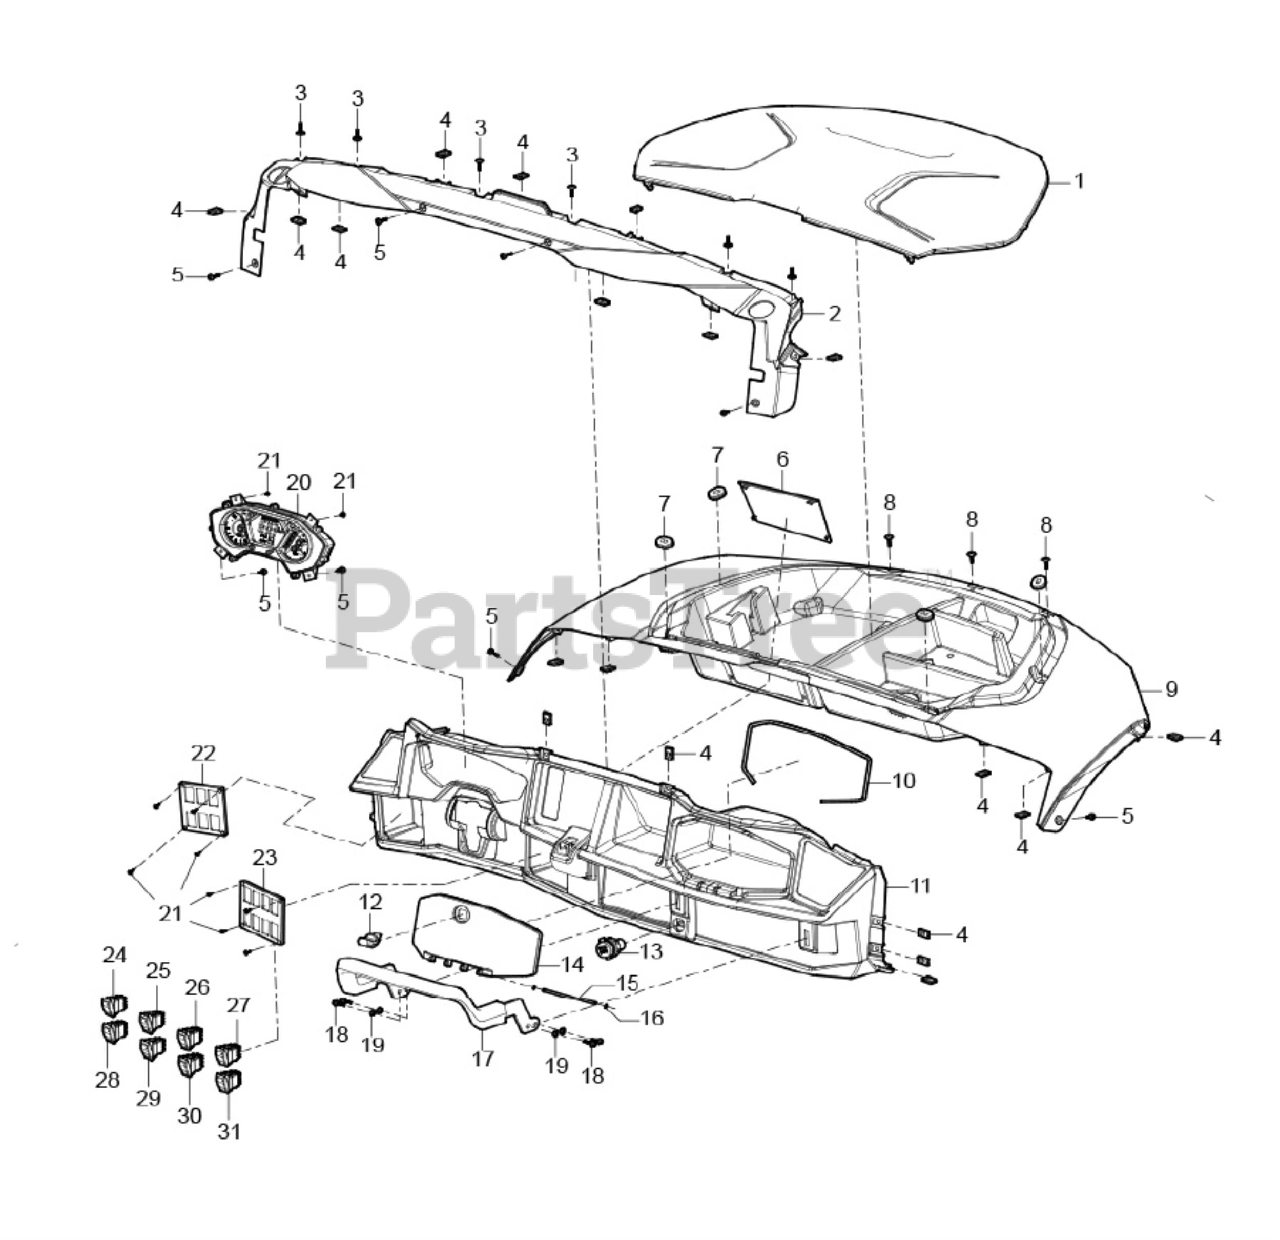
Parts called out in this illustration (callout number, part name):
1	COVER - HOOD
2	DASH COVER SUPPORT
3	CROSS LARGE PLATE HEAD SCREW M6X16
4	CLAMP NUT M6X6
5	SOCKET HEX FLAT HEAD BOLT M6X16
6	DOOR ADJUSTING GEAR SELECTOR CABLE RED
6	DOOR ADJUSTING GEAR SELECTOR CABLE YELLOW
6	DOOR ADJUSTING GEAR SELECTOR CABLE BLUE
6	DOOR ADJUSTING GEAR SELECTOR CABLE BLACK
6	DOOR ADJUSTING GEAR SELECTOR CABLE CAMO
7	RUBBER WASHER 8X17
8	HEXAGON SOCKET HEAD CAP SCREWS M6X16
9	HOOD (RED)
9	HOOD (DARK YELLOW)
9	HOOD (BLUE)
9	HOOD (BLACK)
9	HOOD (G2 CAMO)
10	STORAGE BOX SEALING STRIP
11	DASH ASSEMBLY
12	LOCK STORAGE BOX COVER ASSEMBLY
14	STORAGE BOX COVER
15	STORAGE BOX COVER ROD
18	HEX FLANGE BOLT M8 X 20
19	LOCK NUT M8
20	MAIN METER ASSEMBLY
21	SCREW - SELF TAPPING ST3.9 X 10
22	SWITCH SUPPORT
23	SWITCH SUPPORT I
24	HEAD LIGHT SWITCH
25	SWITCH OVERRIDE
26	SWITCH - 2W/4W
27	SWITCH - FRONT DIFFERENTIAL
28	SWITCH - EMERGENCY LIGHT
29	SWITCH - TURN
30	SWITCH - WINCH
31	SWITCH - REAR DIFFERENTIAL
